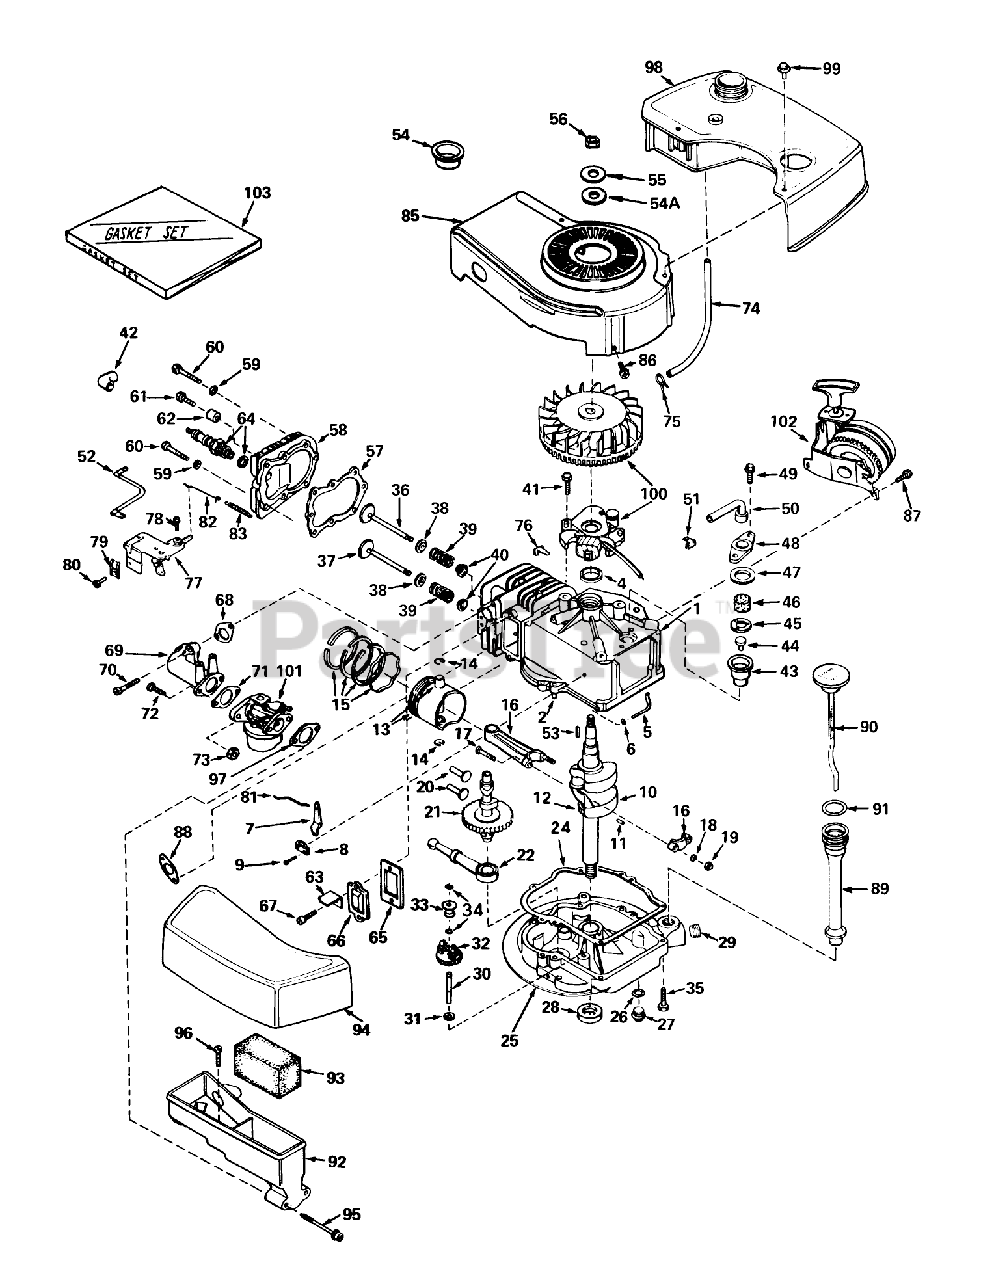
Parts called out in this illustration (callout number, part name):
1	Cylinder Assy. (Incl. Ref. #2, 4 105)
2	Pin-Dowel
4	OIL SEAL
5	Rod, Governor (Incl. No. 36)
6	Washer-Flat
7	Governor Lever
8	Clamp-Lever, Governor
9	Screw
10	Crankshaft Assembly (Incl. Nos. 12 13)
11	Pin, Groove
12	Gear, Crankshaft
13	Piston Pin Assembly (Incl. 2 of No. 14) (.010 Oversize)
13	Piston Pin Assembly (Incl. 2 of No. 14) (.020 Oversize)
14	Ring-Retaining, Piston Pin
15	Ring Set Piston (Std.)
15	Ring Set Piston (.010 Oversize)
15	Ring Set Piston (.020 Oversize)
16	Rod Assy., Connecting (Incl. Ref. #17)
17	Bolt, Connecting
18	Washer
19	LOCKNUT
20	Lifter-Valve
21	Camshaft (Mech. Compression Release)
22	Oil Pump ASM
24	Gasket, Mounting
25	Filter, Air Cleaner
26	Gasket-Oil Drain
27	Plug Oil Drain
28	Seal Oil
29	Plug Oil Drain
30	Shaft-Governor
31	Washer-Flat
32	Governor Gear ASM
33	Spool-Governor
34	Ring-Retaining
35	Screw (1/4-20 x 1-1/4)
36	Valve, Intake (Incl. Ref. #38, 39 40) (Std.)
36	Valve, Exhaust (1/32" Oversize) (Incl. Nos. 8, 9 10)
37	Valve, Exhaust (Standard) (Incl. Nos. 8, 9 10)
37	Valve, Exhaust (1/32" Oversize) (Incl. Nos. 8, 9 10)
38	Cap-Upper Valve Spring
39	Spring-Valve
40	Cap-Valve, Spring
41	Screw
42	Cover-Spark Plug
43	Body Breather Tube
44	Valve Check
45	2000A37 WIZARD ROTA
46	Element-Breather
47	Gasket-Breather
48	Cover Breather
49	Screw, Hex Hd. w/Conical
50	Tube, Breaker
51	Clip, Breather
52	Wire, Ground
53	Key Flywheel
54A	Washer Flat
55	Washer
56	Hex Nut
57	Oil Fill Tube
58	Head Cylinder
59	Washer
60	Screw
61	Screw Hex Hd. Cap
62	Space
63	Retainer Clip
64	Plug, Spark (J17LM or equiv.)
65	Gasket-Breather
66	Cover-Valve
67	Screw
67A	Terminal
68	Gasket, Intake
69	Pipe, Intake
70	Screw (1/4-20 x 1)
71	Gasket-Carburetor
73	Nut and Lock Washer (1/4-28)
74	Line, Fuel
75	Clamp-Line, Fuel
78	Screw (10-24 x 3/4)
79	Conduit
80	Screw (10-32 x 3/8)
81	Link Governor
82	Link Governor Spring
83	Spring Governor
85	Housing, Blower
86	Screw
87	Screw (1/4-20 x 1/2)
88	Gasket Exhaust
89	Tube, Oil Filler
90	Dipstick, OiI (Incl. No. 91)
91	O-Ring
92	Body Air Cleaner
93	Filer, Air
94	Cove, Air Cleaner
95	Screw Fil Hd.
96	Screw, Hex Hd.
97	Gasket-Air Cleaner
98	Tank Fuel
99	Screw (10-32 x 35/64)
100	Magneto
101	Carburetor
102	Starter, Side Mount
103	53024/VAR.16HP O/P
